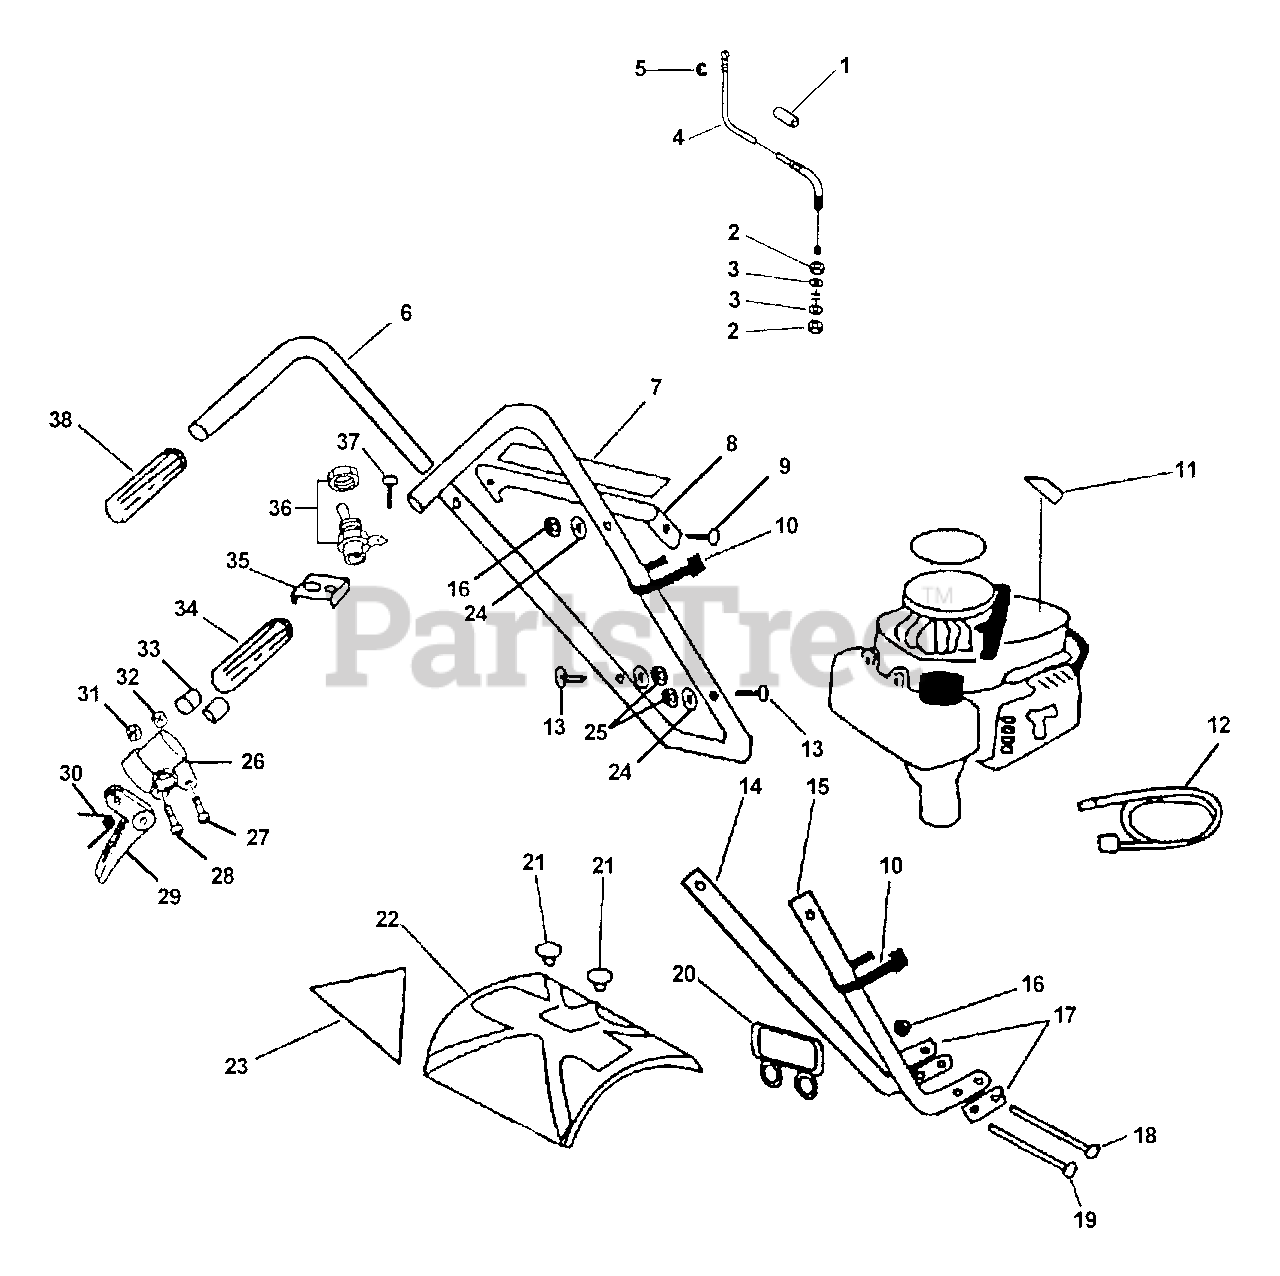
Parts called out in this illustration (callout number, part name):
1	TUBE - VINYL
3	LOCKWASHER - 6
4	CABLE, THROTTLE
5	RING, RETAINING - 7/32"
6	HANDLE - UPPER
7	LABEL - CAUTION
8	BRACKET, HANDLE
9	BOLT - 1/4 X 1-1/4"
10	TIE, CABLE
11	LABEL - MODEL TC-2100 TYPE 1E
12	LEAD - GROUND
13	BOLT - 1/4 X 1-1/4"
14	HANDLE, LOWER - LEFT
15	HANDLE, LOWER - RIGHT
16	LOCKNUT - 1/4"
18	BOLT - 1/4 X 3"
19	BOLT - 1/4 X 3-1/4"
20	HANDLE - FRONT
21	BOLT - 1/4 X 1/2"
22	SHIELD, BLADE
23	LABEL - CAUTION
24	LOCKWASHER
25	NUT - 1/4"
26	BRACKET, TRIGGER
27	SCREW - 5X28
28	SCREW - 5X30
29	TRIGGER, THROTTLE
30	SPRING, TRIGGER
31	LOCKNUT - 5
34	GRIP, HANDLE - RIGHT
35	BRACKET, SWITCH
36	IGNITION SWITCH KIT
37	SCREW - 5X10
38	GRIP, HANDLE - LEFT
